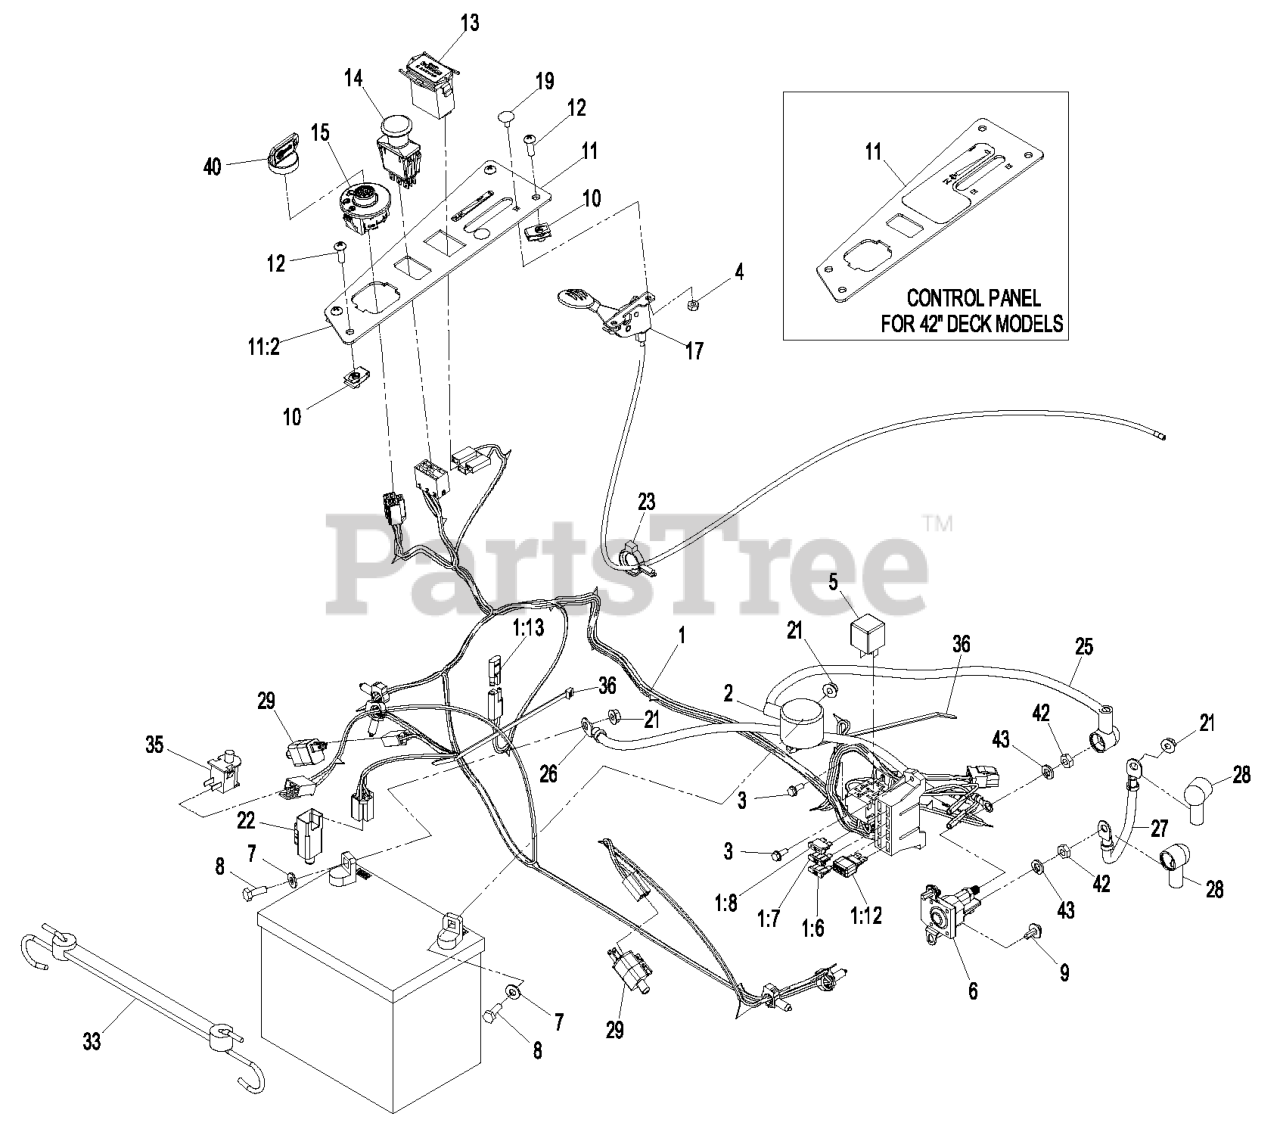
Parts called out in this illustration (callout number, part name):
1	HARNESS,WIRE QUEST
1:6	FUSE-BLADE, 25 AMP
1:7	FUSE-BLADE TYPE, 20 AMP
1:8	FUSE-BLADE, 15 AMP
1:12	DIODE-TVS
1:13	CAP-PLUG
2	INSULATOR-BATTERY
3	SCREW-TAPTITE
4	NUT-LOCK, NI
6	SOLENOID
7	WASHER-FLAT
8	SCREW-HH
9	SCREW-HHFTF
10	Nut, Retainer-Panel 1/4-20
11	ASM,CONTROL PANEL
11:2	DECAL,THROTTLE CHOKE 42
12	SCREW-PRH
13	METER-HOUR
14	SWITCH-PTO
17	CABLE,THROTTLE
19	BOLT-CARR
22	SWITCH-REVERSE
23	CLAMP-HOSE
25	POSITIVE BATTERY CABLE AS
26	CABLE-GROUND, NEGATIVE
27	Asm, Positive Starter Cable
28	INSULATOR-SOLENOID
33	HOLDDOWN-BATTERY
35	SWITCH-BAIL
36	TIE-CABLE
40	KEY-IGNITION
41	CLIP-HARNESS
42	NUT-JAM
43	WASHER-LOCK
